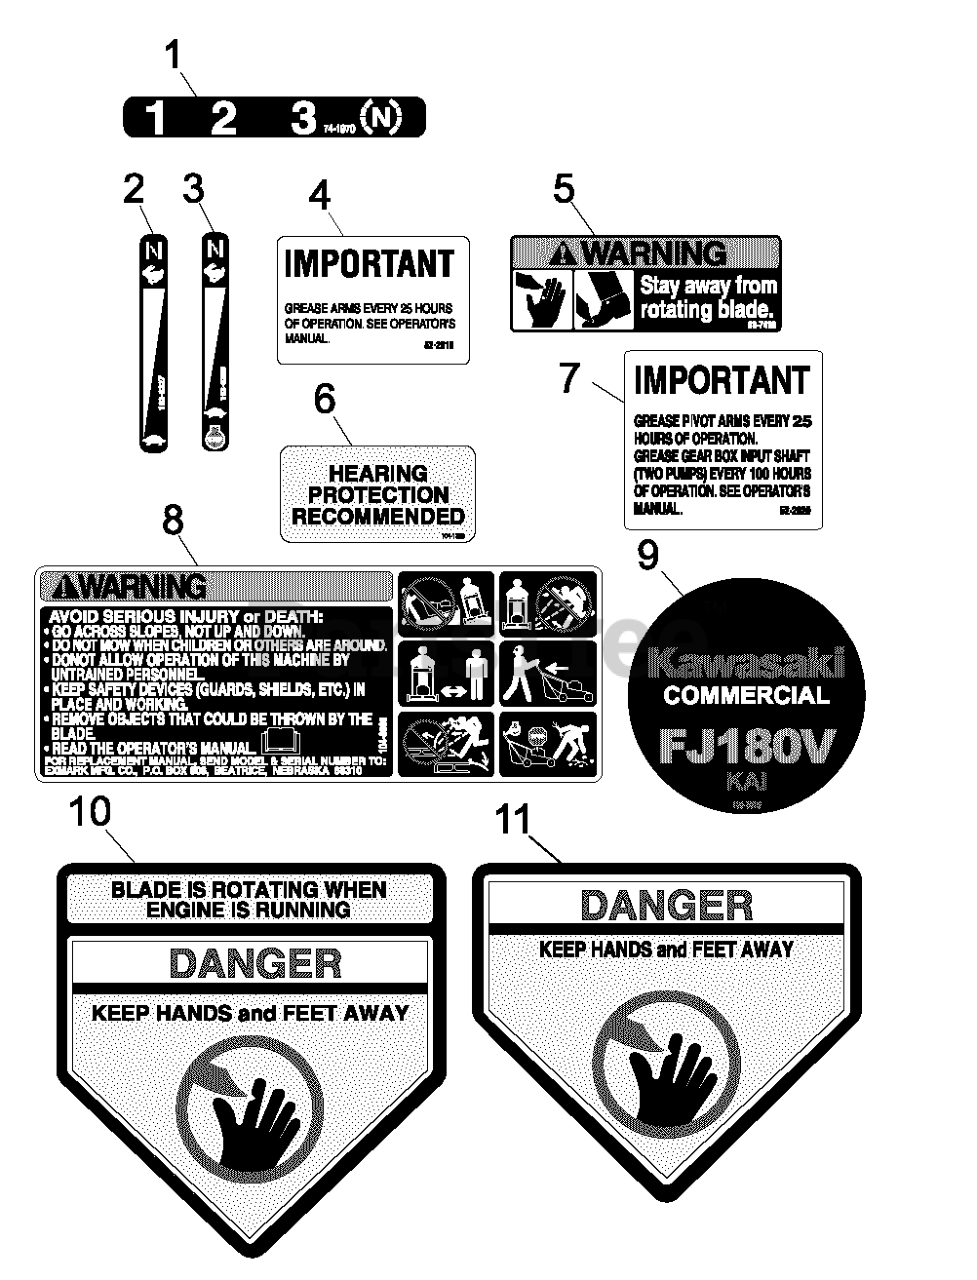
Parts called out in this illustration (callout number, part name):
1	DECAL-POSITION, GEAR
2	DECAL,THROTTLE/CHOKE
3	DECAL-THROTTLE / CHOKE
4	LABEL-GREASE, HP
5	DECAL-BLADE
6	DECAL-PROTECTION, HEARING
7	Label, Grease
8	DECAL-WARNING
9	DECAL
10	DECAL-DANGER
11	DECAL-DANGER
